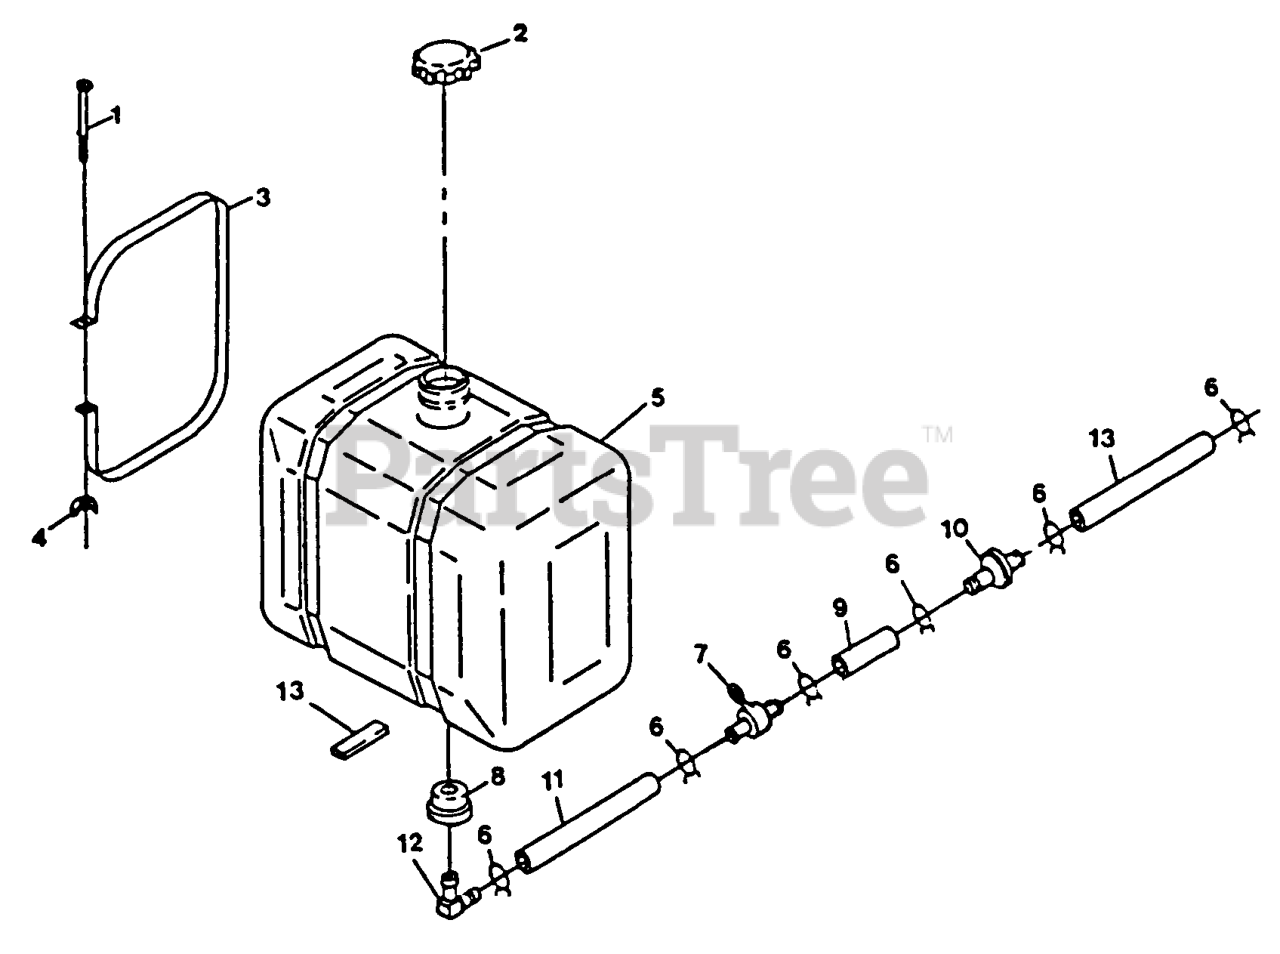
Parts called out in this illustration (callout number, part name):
1	SCRW,MACH CRPH
2	CAP-FUEL
4	WINGNUT
7	VALVE-FUEL
11	HOSE-FUEL
12	ELBOW-TANK, FUEL
